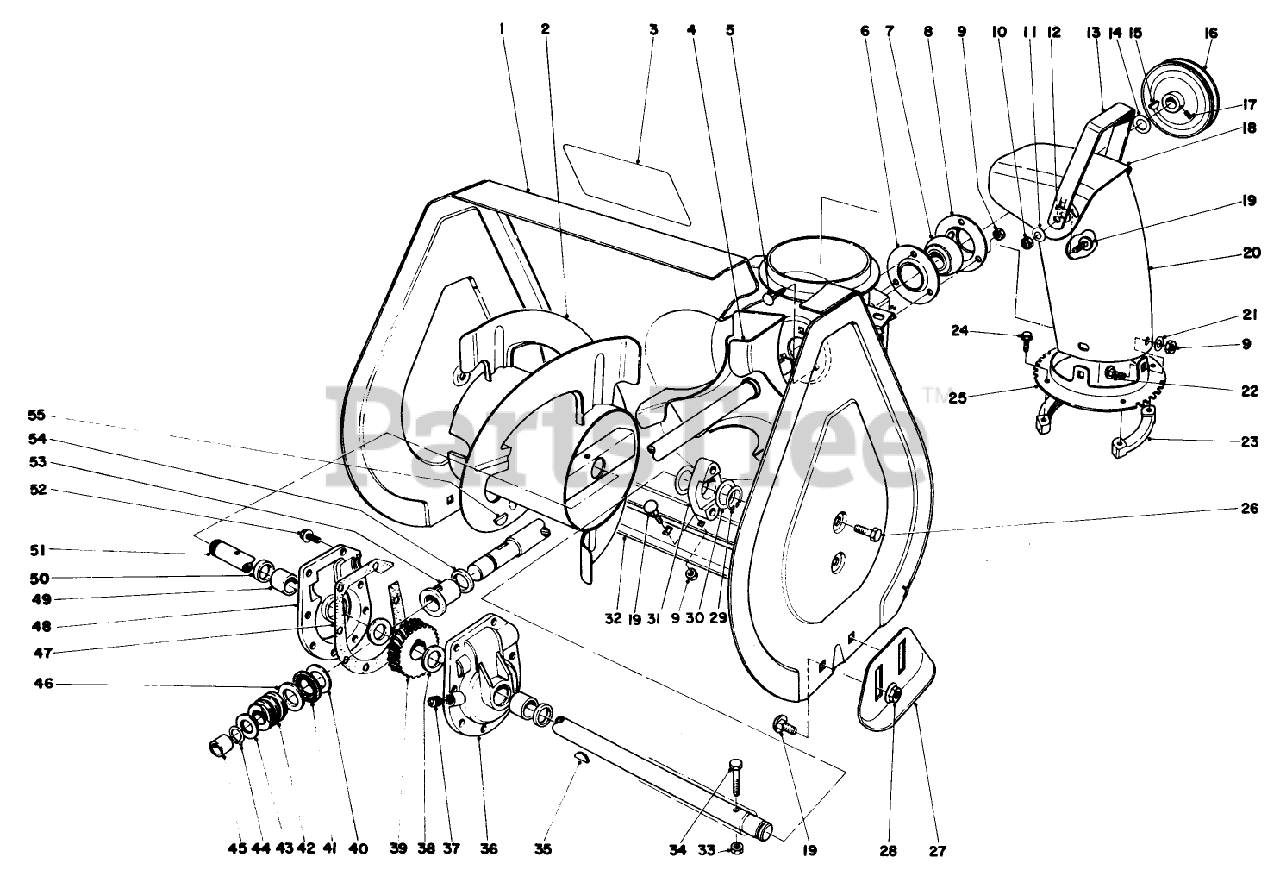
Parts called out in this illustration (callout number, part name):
1	Auger Housing
2	Auger R.H.
3	Decal-Warning
4	Shaft & Impeiler
5	BOLT-CARR
6	FLANGE-CUP, BEARING
7	Ball Bearing
8	FLANGE-CUP, BEARING
9	NUT-LOCK, NI
10	NUT-LOCK, CONE
11	WASHER-BELLEVILLE
12	WASHER-RUBBER
13	Handle Deflector
14	WASHER
15	KEY-WOODRUFF
16	PULLEY
17	SCREW-SET, SQH
18	Deflector
19	BOLT-CARR
20	Chute-Discharge
21	WASHER-PLAIN
22	SCREW-CARR
23	RING-CHUTE, RETAINER
24	SCREW-SPECIAL
25	Chute Ring
26	SCREW-HWHTF
27	Skid
28	NUT-HF
29	RING-RETAINING
30	WASHER
31	BEARING-AUGER
32	Blade-Scraper
33	NUT-LOCK, CONE
34	SCREW-HH
35	KEY-WOODRUFF
36	Gear Case L.H. (Incl. Ref. #49 & 50)
37	PLUG-PIPE, SQH
38	WASHER-THRUST
39	Gear
40	WASHER-THRUST
41	BEARING-THRUST
43	WASHER-THRUST
44	Ring-Snap
45	BUSHING
46	WASHER-THRUST
47	asket
48	Gear Case R.H. (Incl. Ref. #49 & 50)
49	BUSHING
50	SEAL-OIL
51	AUGER SHAFT
52	SCREW-TAPTITE
53	BUSHING-INPUT
54	RING-QUAD
55	KEY-WOODRUFF
